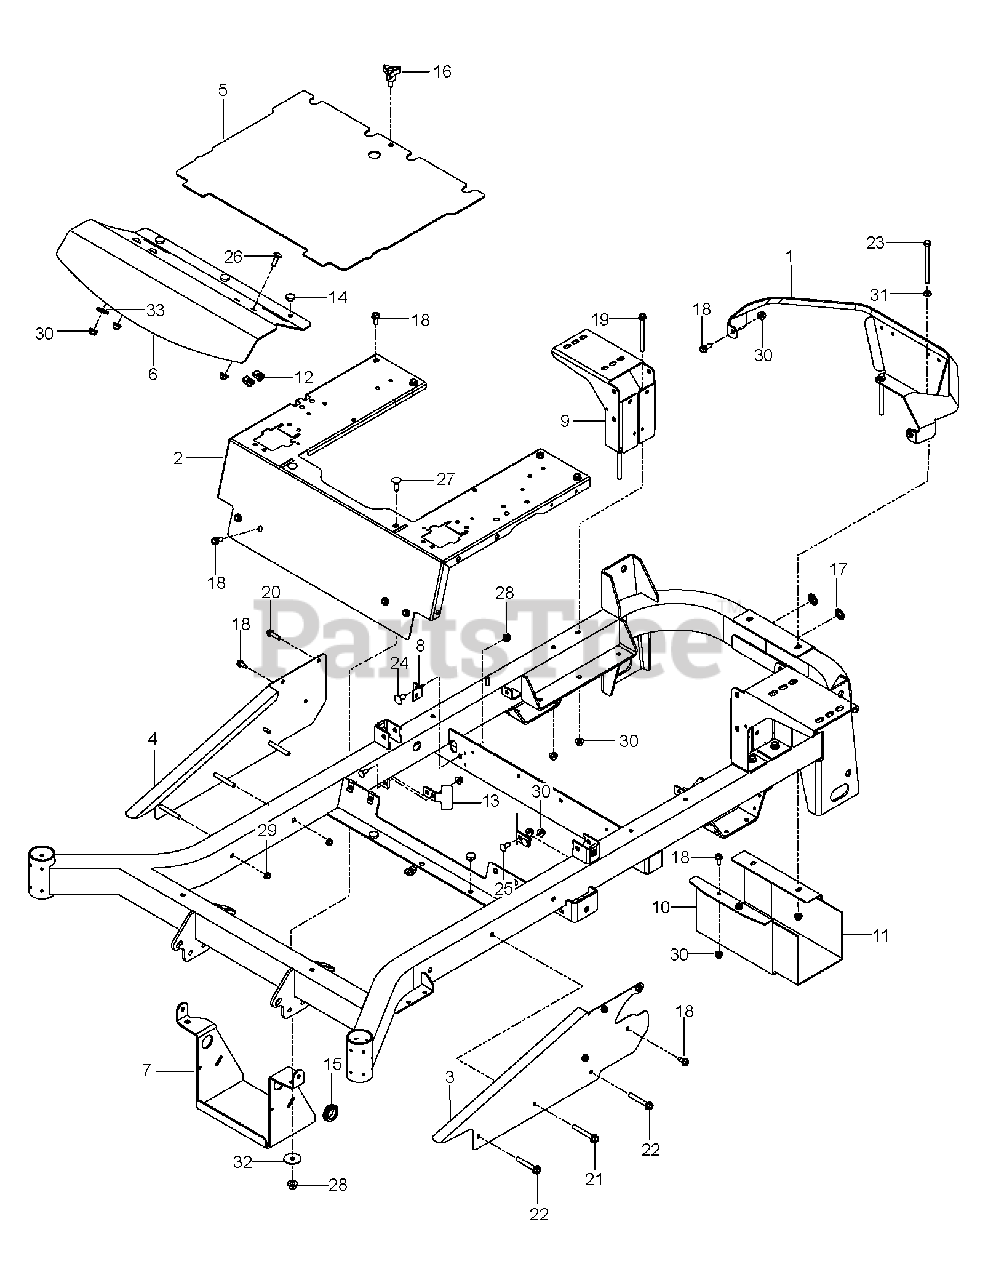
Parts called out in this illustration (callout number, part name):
1	GUARD.PNT.REAR.MZ.GRAY
2	SUPPORT.PNT.SEAT.CONTROL.ORNG
3	SIDE.LT.ORANGE
4	SIDE.RT.ORANGE
5	PLATE, FLOOR W/DECALS
6	PLATE, FOOTREST
7	BRACKET.PNT.BATTERY.BLK
8	BRACKET.DAMPENER.BLACK
9	MOUNT, TANK, ZT BLK
10	SHIELD.MUFFLER.BLACK
11	HEAT SHIELD
12	U-CLIP 5/16-18 NUT RETAINER
13	STOP, DECK, EZ+
14	GROMMET, BUMPER
15	RUBBER GROMMET
16	KNOB W/STUD
17	CAP.PLUG.BP-1.BLACK
18	HHFS 5/16-18 X 3/4
19	BOLT.HEX.FLNG.5/16-18X3.75
20	HHFS 5/16-18 X 1.25 TPBLT GD 5
21	HHFS 3/8-16 X 2-3/4 GR5 ZD
22	HHFS 3/8-16 X 2.5 GR 5 ZD
23	HCS 5/16C X 4
24	RHSNB 3/8-16 X 3/4 GR 5 BLK ZN
25	BOLT 5/16C X 3/4" CARRIAGE
27	BOLT D
28	NUT 3/8-16 HEX FLG NYLOC ZD
29	NUT HEX 3/8-16 NYLON, THIN
30	5/16-18 NYLOC FLANGE NUT
31	WASHER
32	WASHER.13/32X1-1/2X16GA
33	WASHER 1/2" FLAT
